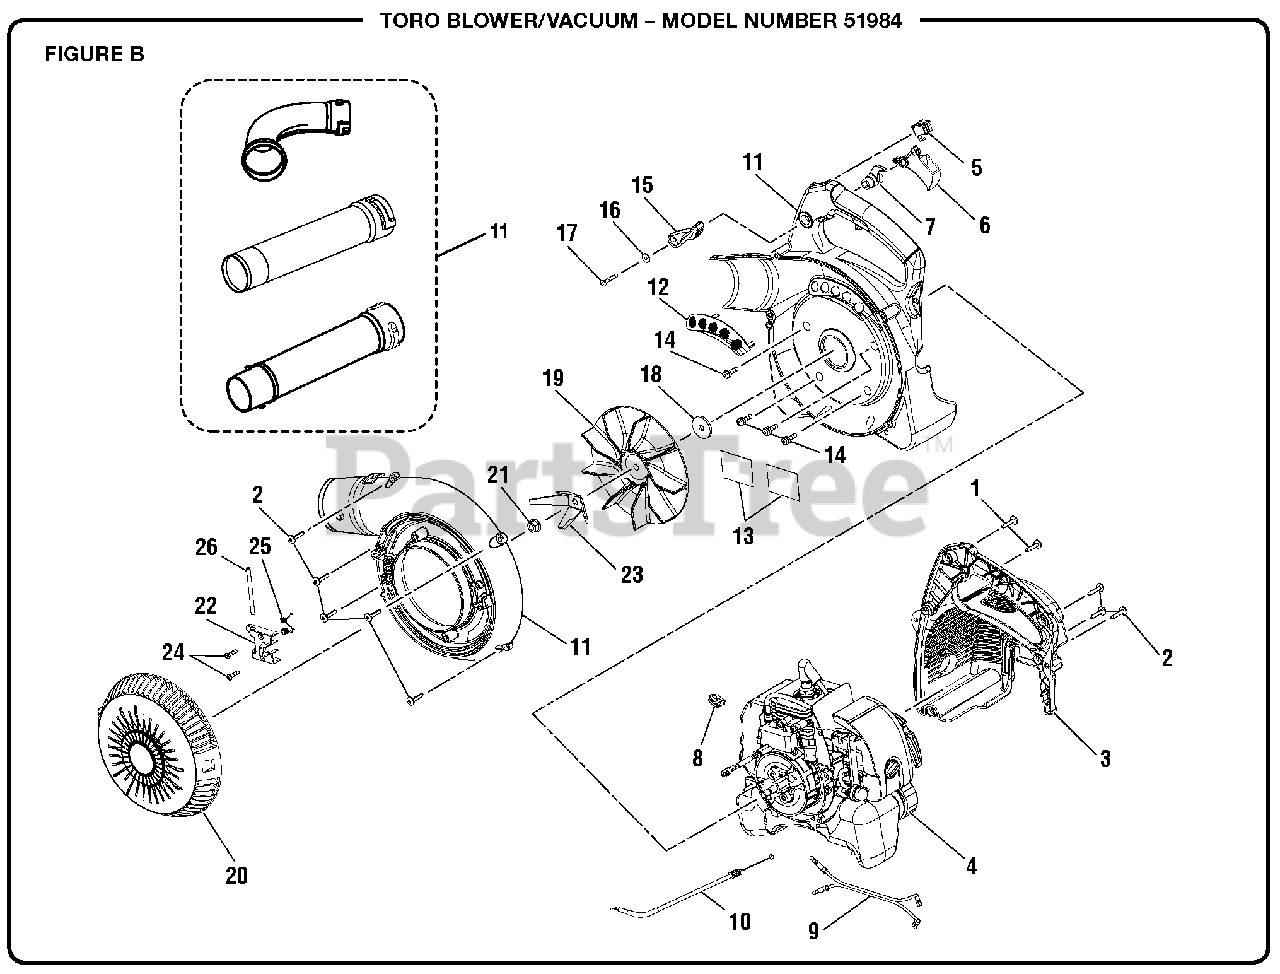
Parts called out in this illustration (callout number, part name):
2	Screw (10-14 x 7/8 in.)
3	Engine Shroud
5	Engine Switch
6	Throttle Trigger
7	Throttle Lock (Cruise Control)
8	Rubber Grommet
9	Wire Harness
10	Throttle Cable
11	Housing and Tube Assembly Kit
12	Mesh Screen
13	Heat Shield Tape
14	Screw (M5 x 20 mm)
15	Cruise Control Lever
16	Washer (Steel)
17	Screw (8-14 x 1 in.)
19	Fan
20	Vacuum Door
21	Lock Nut (M8 x 1.25)
22	Vacuum Door Hinge
23	Mulcher Blade
24	Screw (8-14 x 5/8 in.)
25	Hinge Spring
